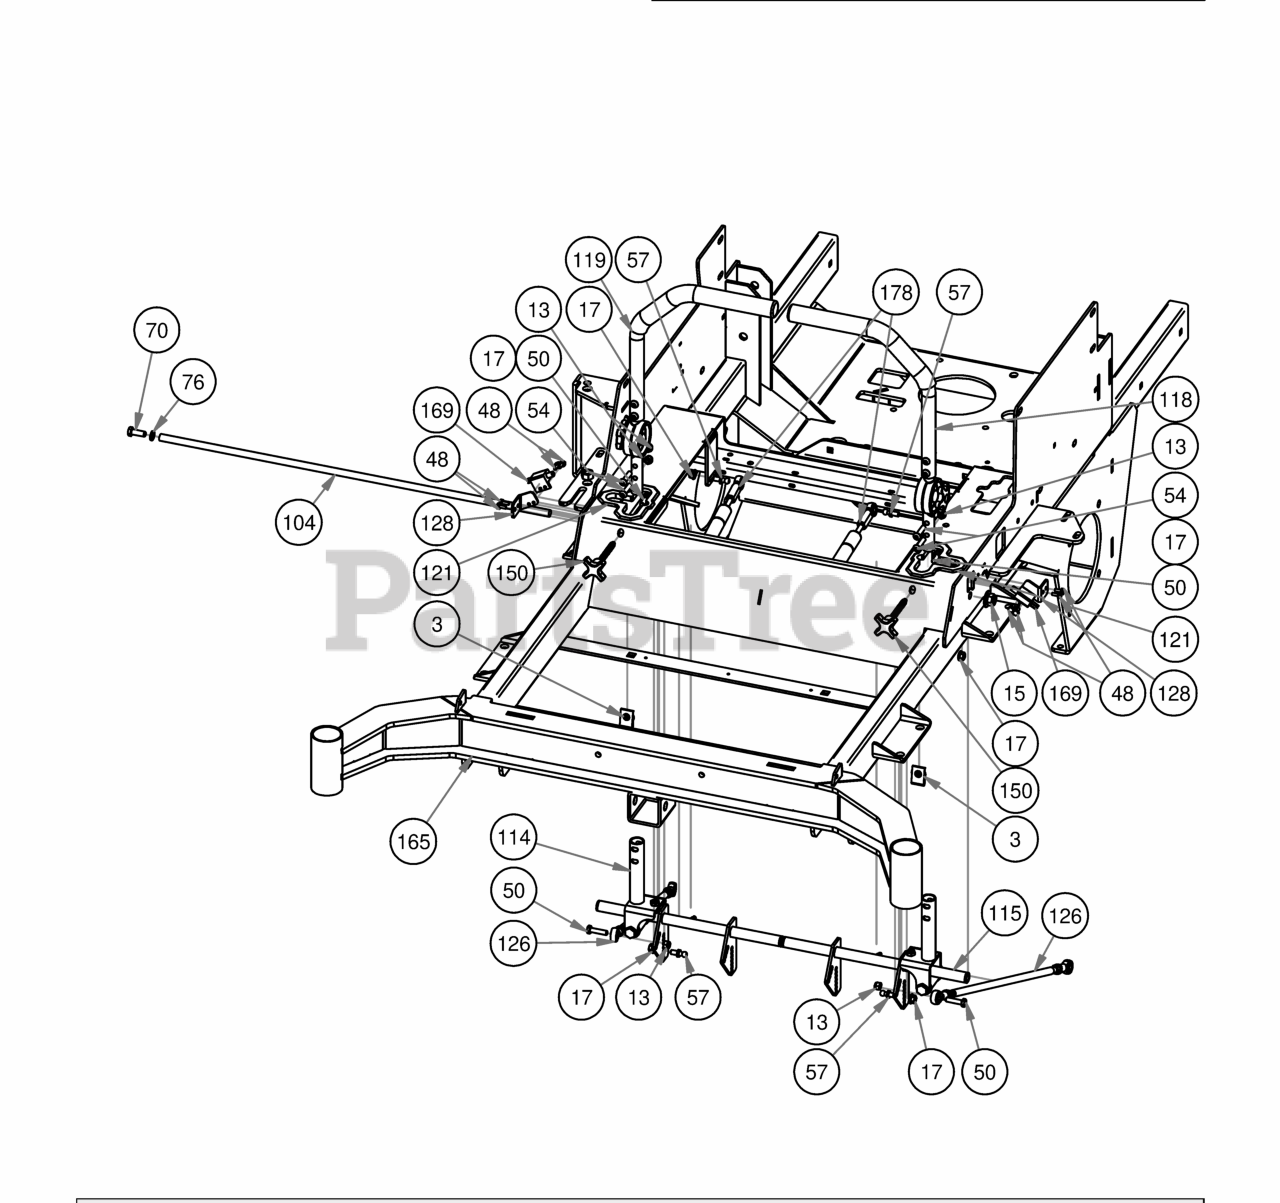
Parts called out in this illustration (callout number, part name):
3	Extruded Nut 3/8"-16 3/4" Hole Center With Patch
13	5/16-18 Nylock Insert Locknut
15	1/2-13 Nylon Flange Nut
17	5/16" Flange Nut
48	12-24x 1/2 HWH Bolt
50	5/16 x 1 1/4 Hex Bolt
54	5/16-18 UNC X 1-3/8" BHCS, TORX DRIVE, GR 5
57	10mm Damper Ball Stud-Steering
70	3/8" x 1" Hex Bolt
76	3/8" Lock Washer
104	2019 Steering Actuator Rod
114	2019 R Series RH Arm Rod Assembly
115	2019 R Series LH Arm Rod Assembly
118	2019 Left Hand ADJ. Steering Arm Kit
119	2019 Right Hand ADJ. Steering Arm Kit
121	Snap-In Bushing-2019
126	2019 Outlaw Rigid Push Rod Assembly
128	2019 Arm Switch Bracket
150	Speed Limiting Knob 3/8-16X 3"
165	2019 Rigid Frame
169	Safety Switch
178	Steering Damper
